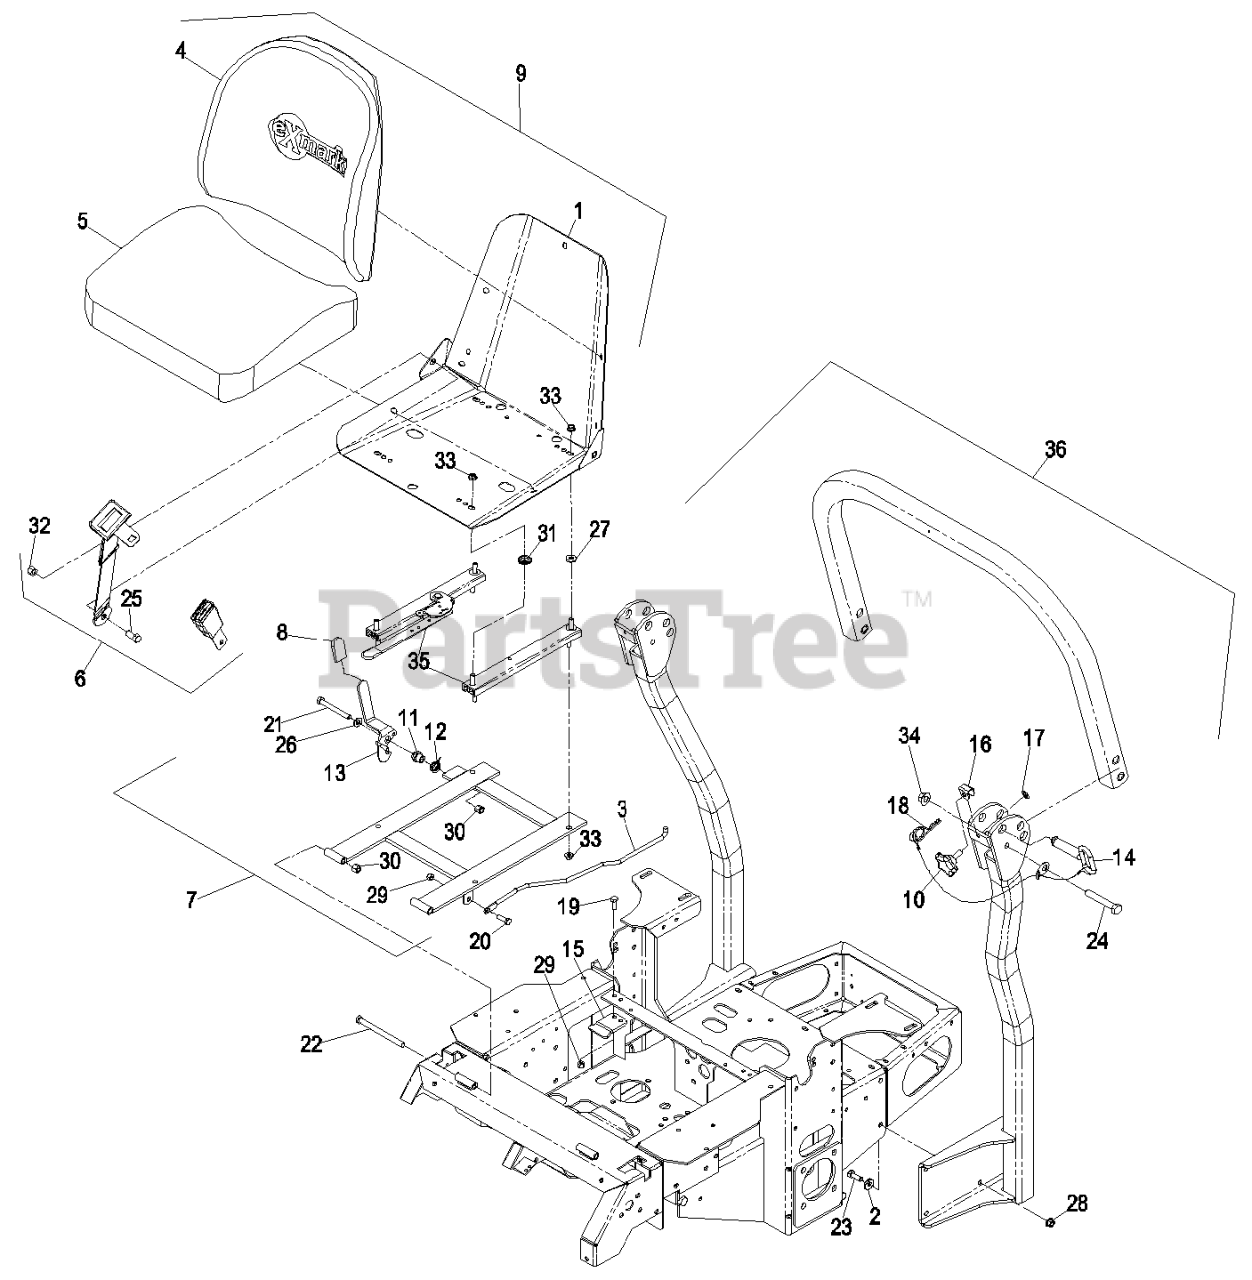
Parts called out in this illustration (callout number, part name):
1	FRAME-SEAT
2	WASHER-BELLEVILLE
3	ROD-RETAINER, SEAT
4	CUSHION,SEAT BACK
5	CUSHION,SEAT BOTTOM
6	SEATBELT KIT
7	ASM,SEAT FRAME
8	GRIP-LEVER
11	BUSHING-LATCH, SEAT
12	SPRING-TORSION
13	LATCH ASM
14	PIN-FOLD, ROPS
15	CATCH-LATCH, SEAT
17	NUT-PUSH
18	HAIRPIN
19	SCREW-HH
20	SCREW-HH
21	SCREW-HH
22	SCREW-HH
23	SCREW-HH
24	SCREW-HH
25	SCREW-HH
26	WASHER-FLAT
27	WASHER-FLAT
28	NUT-HHF, WHIZ
29	NUT-LOCK, NI
30	NUT-LOCK, NI
32	NUT-LOCK
35	TRACK-SEAT
36	SPACER-TRACK
36	KIT, LAZER HP / CT 2 POST
